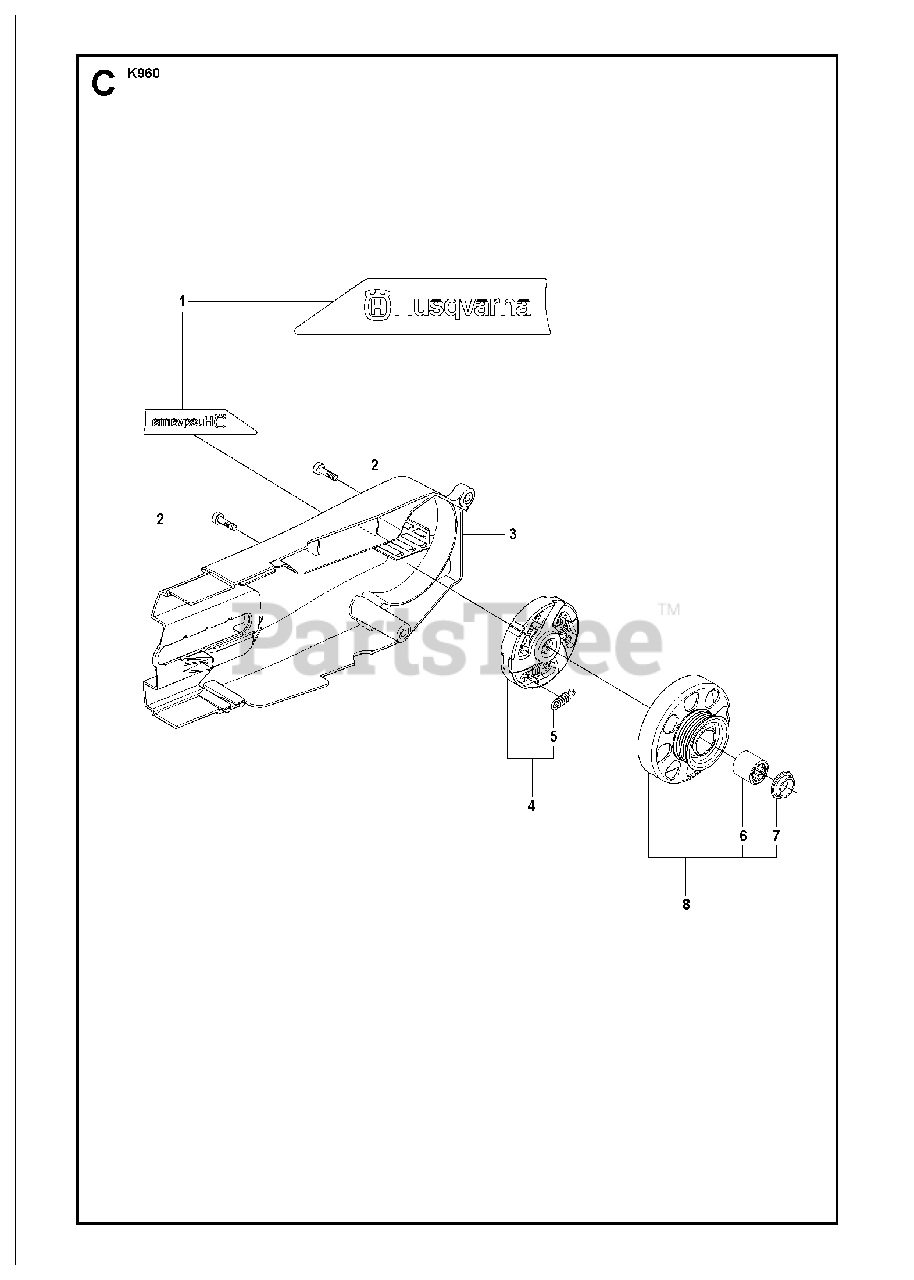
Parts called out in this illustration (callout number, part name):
2	SCREW ITXSCM
3	BELT GUARD
4	CLUTCH ASSYIncl. 5
5	CLUTCH SPRING
6	NEEDLE BEARING
8	DRIVING PULLEY ASSY"12"", 14"". Incl. 6, 7"
8	DRIVING PULLEY ASSY"16"". Incl. 6, 7"
